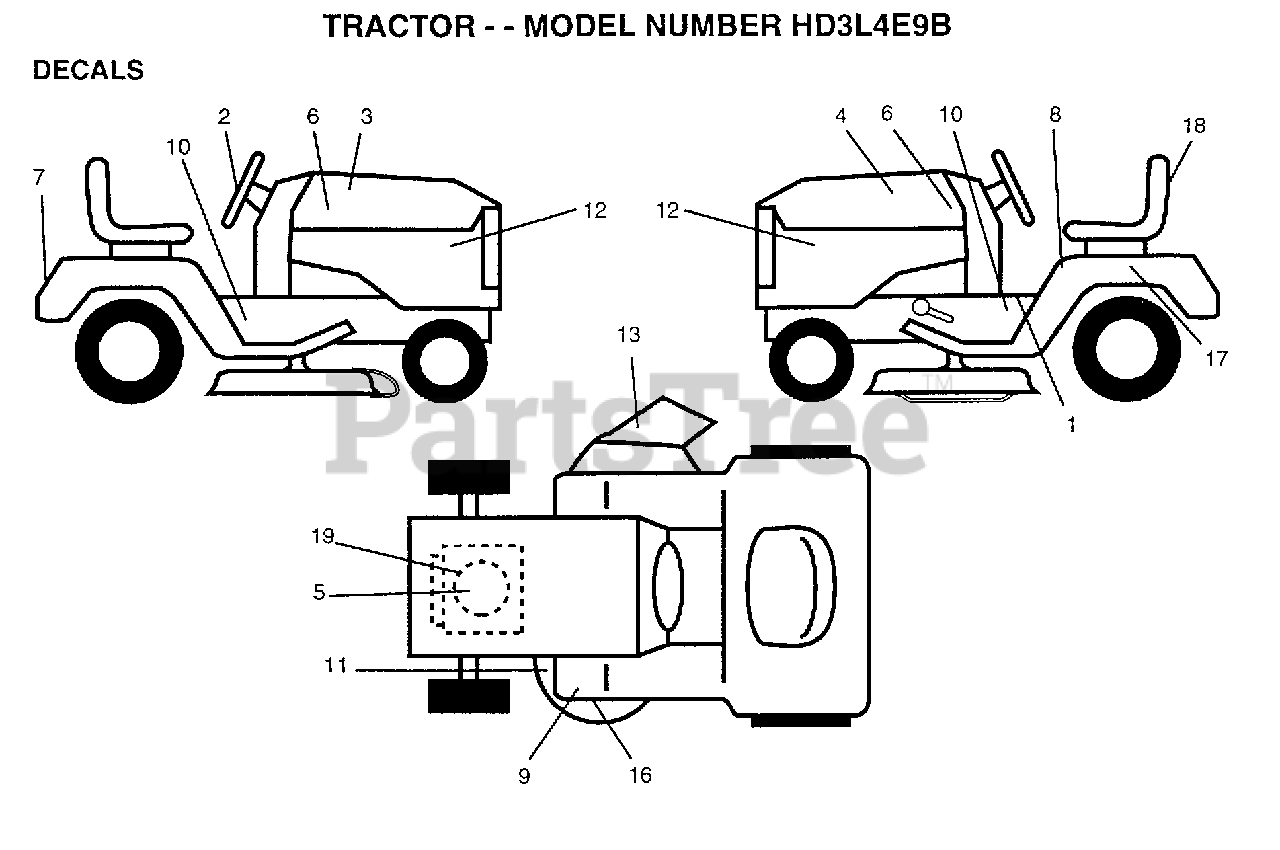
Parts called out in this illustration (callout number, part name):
1	DECAL.SADDLE.INST
2	DECAL.INST.WHL.ST
3	DECAL.HD.RH.16/42
4	DECAL.HD.LH.16/42
5	DECAL, HP ENGINE
6	DECAL.FEND.QUICKS
7	DECAL.FENDER.HDEP
8	DECAL CAUT FEND
9	DECAL CLUT/BRAKE
10	DECAL.SCH.DRV.42
11	DECAL.SCH.PRIM.42
12	DECAL.PNL.SD.HDPO
13	"DECAL, WARNING"
16	DECAL.DECK.MULCH.
17	DECAL.BTRY.DANGER
18	DECAL SEAT ACC
19	DECAL.PARTS.16HP
